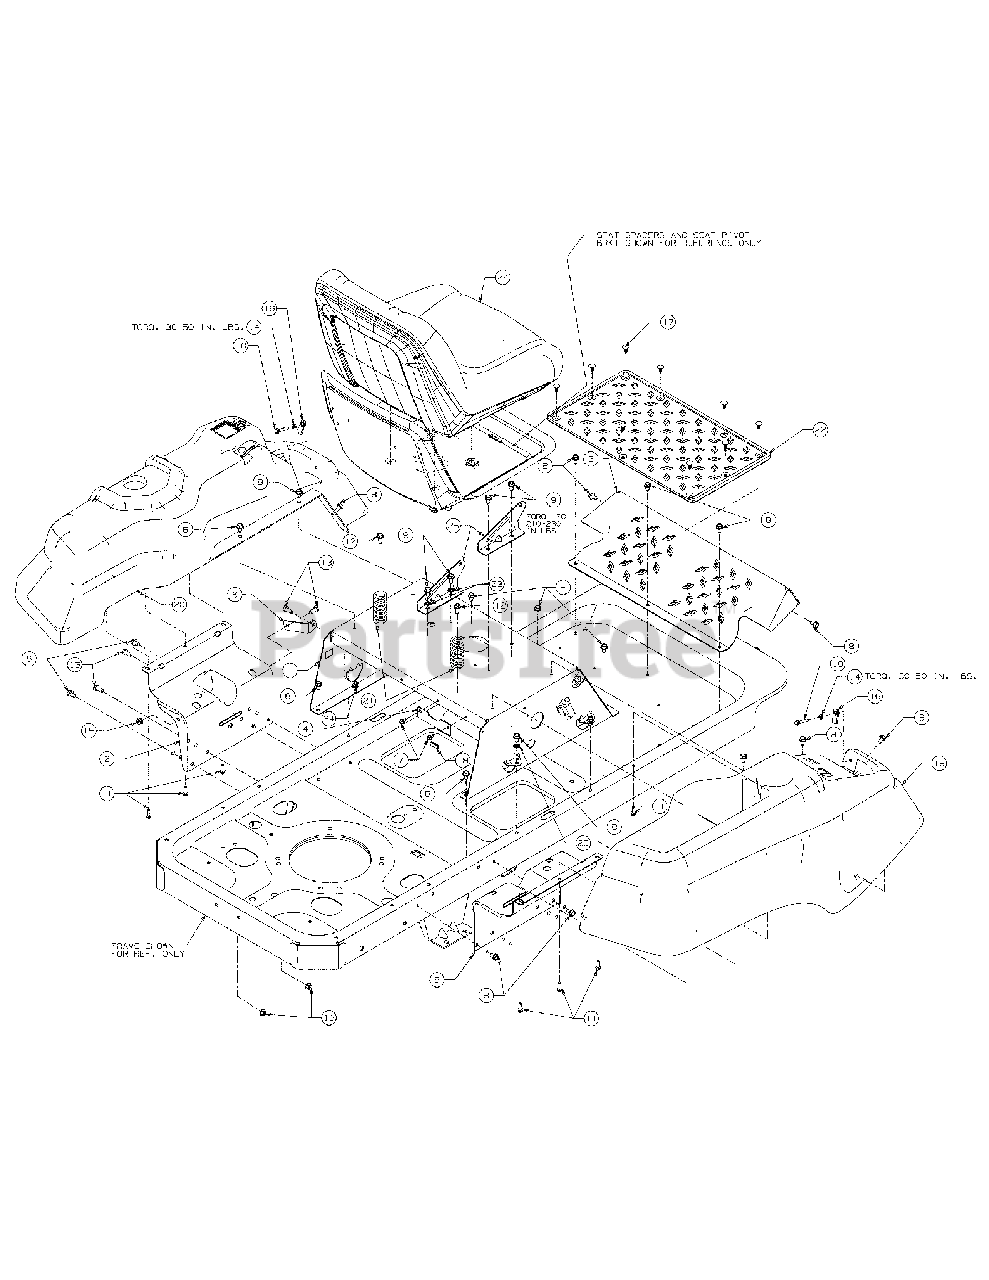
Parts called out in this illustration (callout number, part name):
8	Hex Screw, 5/16-18 x .625
9	Hex Screw, 5/16-12 x .75
10	Hex Screw, 1/4-20 x 1.5
11	Hex Screw, 1/4-15 x .75
12	Hex Screw, 5/16-18 x .75
13	Hex Screw, 5/16-18 x .75
14	Hex Nut, 1/4-20
15	Flange Lock Nut 5/16-18
16	U-Type Nut 1/4
17	Ratchet Clip
18	Trim Strip
19	Right Hand Console
20	Left Hand Console
21	Compression Spring, 1.28 x 3.125
22	Foot Pad
23	External Tooth Washer, 3/8
